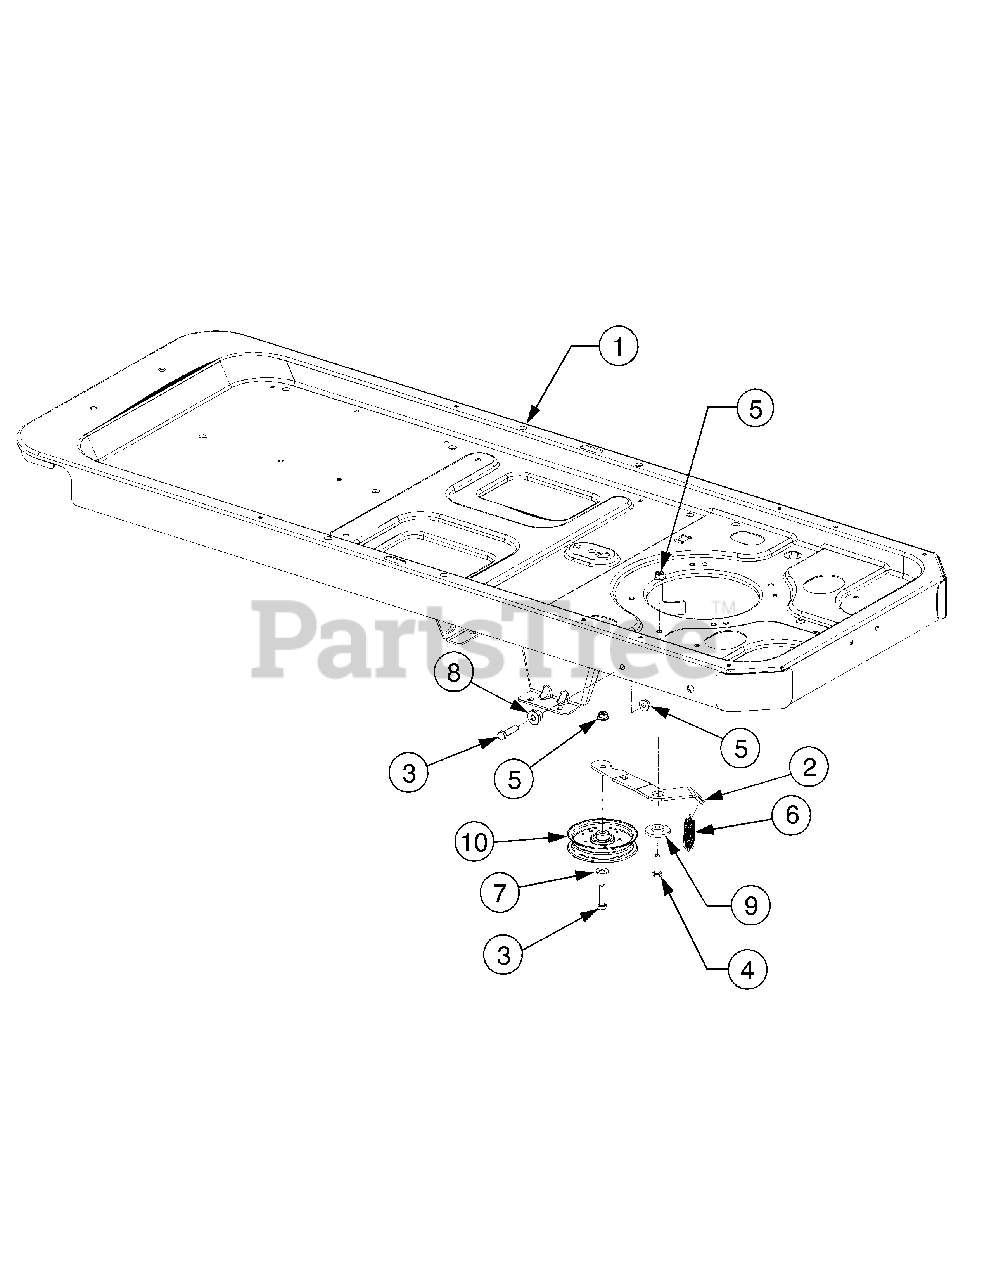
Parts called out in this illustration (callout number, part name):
1	Frame Assembly
2	Idler Arm, Drive
3	Hex Screw 3/8-16 x 1.50
4	Hex Bolt 3/8-16 x 1.25
5	Flange Lock-Nut 3/8-16 Gr. F Nylon
6	Ext. Spring 5.06" Lg.
7	Flat Washer .385 ID x .87 OD x .06
8	Shoulder Spacer .38 x 1.0 x .70
9	Shoulder Spacer .884 x .190
10	Idler Pulley w/Flange 4.25 Dia
